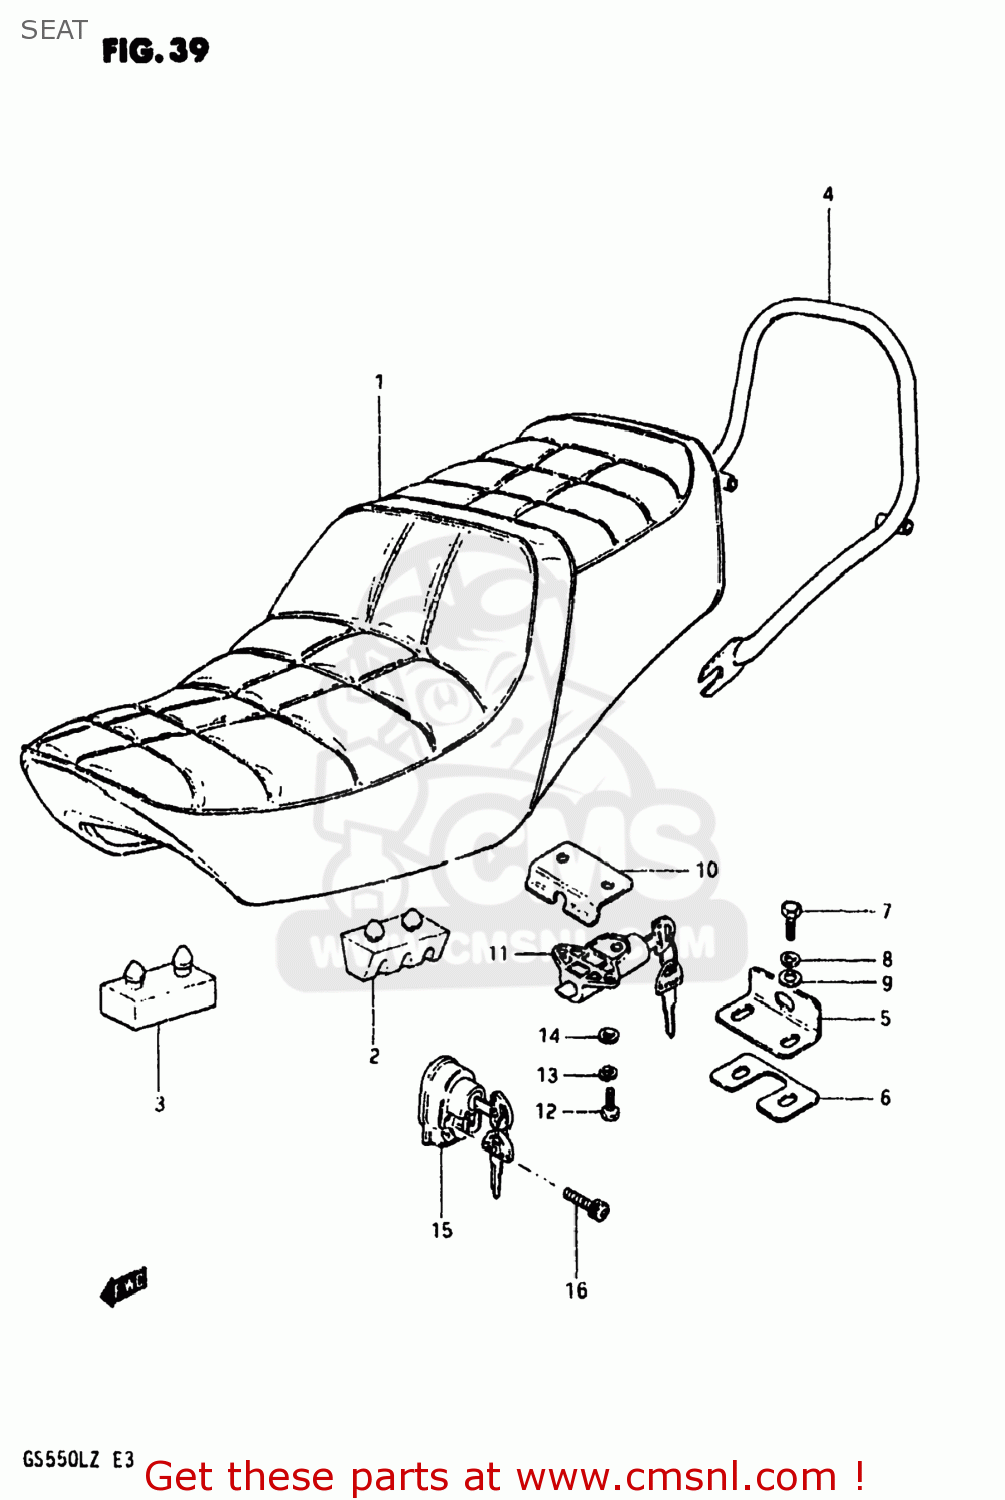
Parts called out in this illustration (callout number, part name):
1	SEAT ASSEMBLY
2	CUSHION,SUPPORT(50X25X32)
3	CUSHION
4	HANDLE,PILLION RIDER
5	STRIKER, SEAT LOCK
6	SHIM,SEAT LOCK STRIKER
7	BOLT, UPPER
8	LOCK WASHER
9	WASHER
10	GUIDE, PLATE
11	LOCK ASSEMBLY,SEAT
12	BOLT
13	LOCK WASHER
14	WASHER
15	LOCK ASSY,HELMET
16	BOLT 5X25
